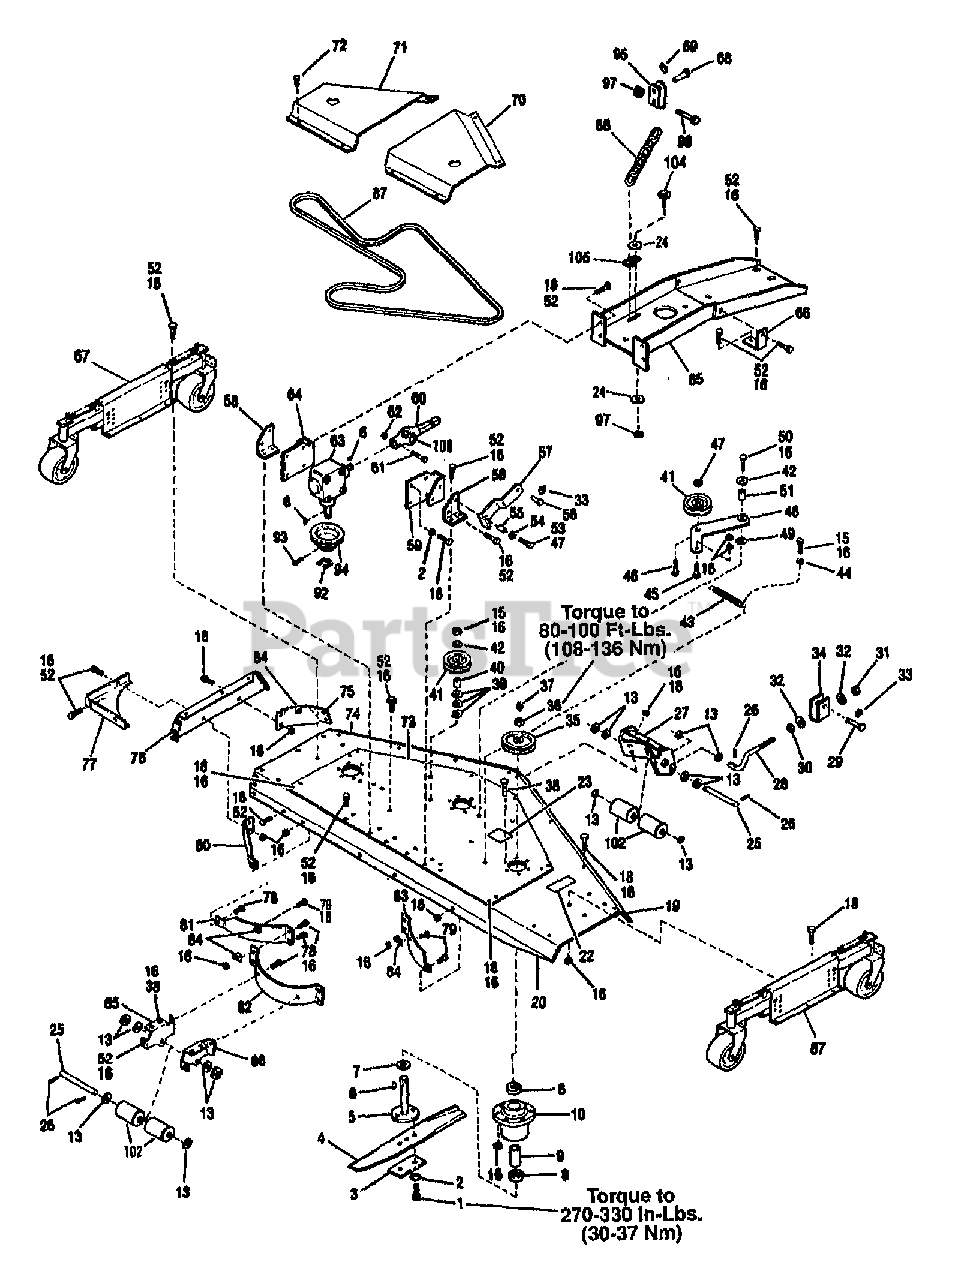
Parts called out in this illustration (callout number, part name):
1	SCR-HH 3/8-24X1.0 G5 ZP
2	WASHER-LK .375 @ DEPL
3	PLATE-BLADE
5	ASSM-BLADE SHAFT
6	KEY-WOODRUFF .25X.875
7	SHIM-1.25X1.01X.06
8	BEARING-BALL
9	SLEEVE
10	HOUSING-SPINDLE
13	WASHER-1.5X.812X.134 ZP
15	SCR-HH 3/8-16X2.0 G5 ZP
16	NUT-LOCK 3/8-16
18	SCR-HH 3/8-16X.75 G5 ZP
19	BASE-FRONT RH
22	DECAL-CUTTING LINE
23	DECAL-BELT DRIVE
24	WASHER-FLAT 5/16 SAE
25	SHAFT-ROLLER
26	PIN-COTTER .120X1.25 ZP
27	BRKT-DRAG FRONT
28	LINK-HITCH
29	PIN-CLEVIS .62X2.50 ZP
30	NUT
31	NUT-H/LK 3/4-10
32	WASHER-LK 1.264X.76X.188
33	RING-COTTER
35	SHEAVE-BLADE
36	NUT-H/LK
37	FITTING-GREASE 1/4-28X2.00
38	SCR-HH 3/8-16X1.25
39	WASHER-1.12X.378X.125
40	SPACER-.5X.385X.437
41	PULLEY-IDLER
42	WASHER-.986X.437X.083 ZP
43	SPRING-EXTENSION
44	NUT-HEX/JAM 3/8-16
47	NUT-TOP LOCK 1/2-13 ZP
48	ARM-IDLER
49	WASHER
50	SCR-HH 3/8-16X1.5 G5 ZP
52	SCR-HH 3/8-16X1.0 G5 ZP
53	SCR-HH 1/2-13X1.75 G5 ZP
54	WASHER-1/2 FLAT
55	SPACER-TUBULAR
56	PIN-CLEVIS .625X1.44
57	LINK-DRAG
58	BRKT-MOUNTING
59	BRKT-GEAR BOX RH
60	ASSM-DRIVE
61	SCR-HH 1/4-20X2.0 G5 ZP
62	NUT-HT LK 1/4-20
63	RT. ANGLE GEAR BOX
64	BRKT-GEAR BOX LH
65	BASE BRIDGE
66	BRKT-SUPPORT
67	GAGE WHEEL ASSY
68	PIN-CLEVIS .375 X .937 ZP
70	COVER-BELT RH
71	COVER-BELT LH
72	SCR
73	DOUBLER-BASE
74	BASE-FRONT LH
75	BAFFLE-FRONT CORNER
76	BASE-END
77	PLATE-BAFFLE
78	SCR-CARR 3/8-16X1.00
79	BOLT-3/8-16 X 3/4
80	BAFFLE-REAR CORNER
84	BRKT-BAFFLE
85	BRKT-ROLLER LH
87	BELT-V
88	CHAIN
92	RING-RETAINING
93	SCR-SQ HD SET 5/16X3/4
94	SHEAVE-DRIVE
97	NUT-H/LK 5/16-18
98	SCR-HH 5/16-18X1.25 G5ZP
104	SCR-HFLK 5/16-18X1.00 ZP
108	KIT-CROSS REPAIR
